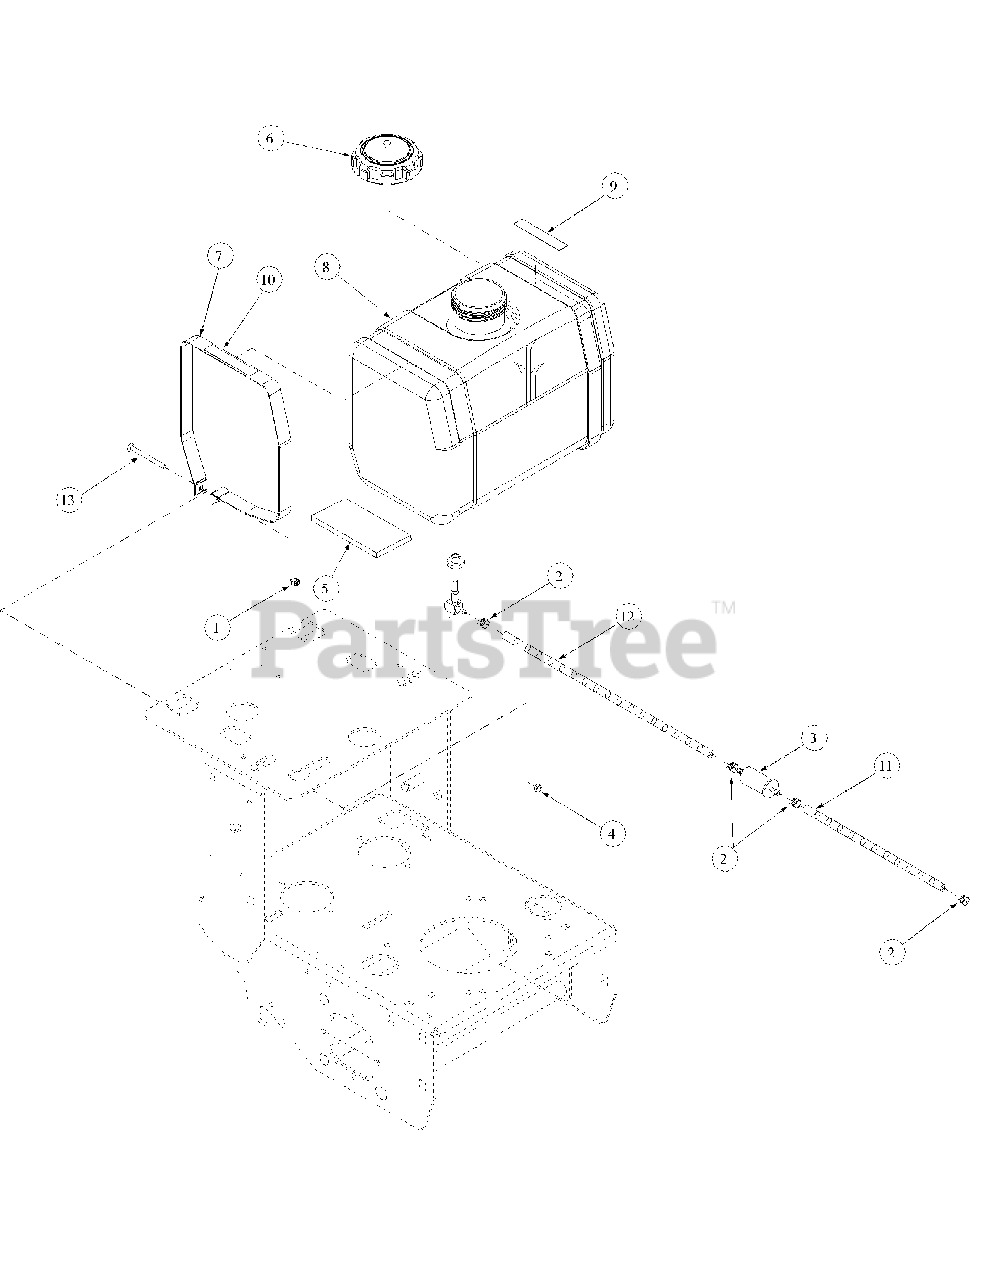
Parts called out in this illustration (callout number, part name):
1	Lock Nut, Nylon Insert, 1/4-20 Grade A
2	Uni-Clamp, #5077-136
3	Fuel Filter, Kohler
4	Nut, 1/4-20, Grade A
5	Stop Pad, Rubber
6	Fuel Cap, 3.5
7	Fuel Tank Strap
8	Fuel Tank
9	Mower Warning Label, Turn off Engine
10	Mower Instruction Label, Fuel Valve
11	Fuel Hose, 12"
12	Fuel Hose, 18"
13	Carriage Bolt, 1/4-20 x 3.00 Grade 5
